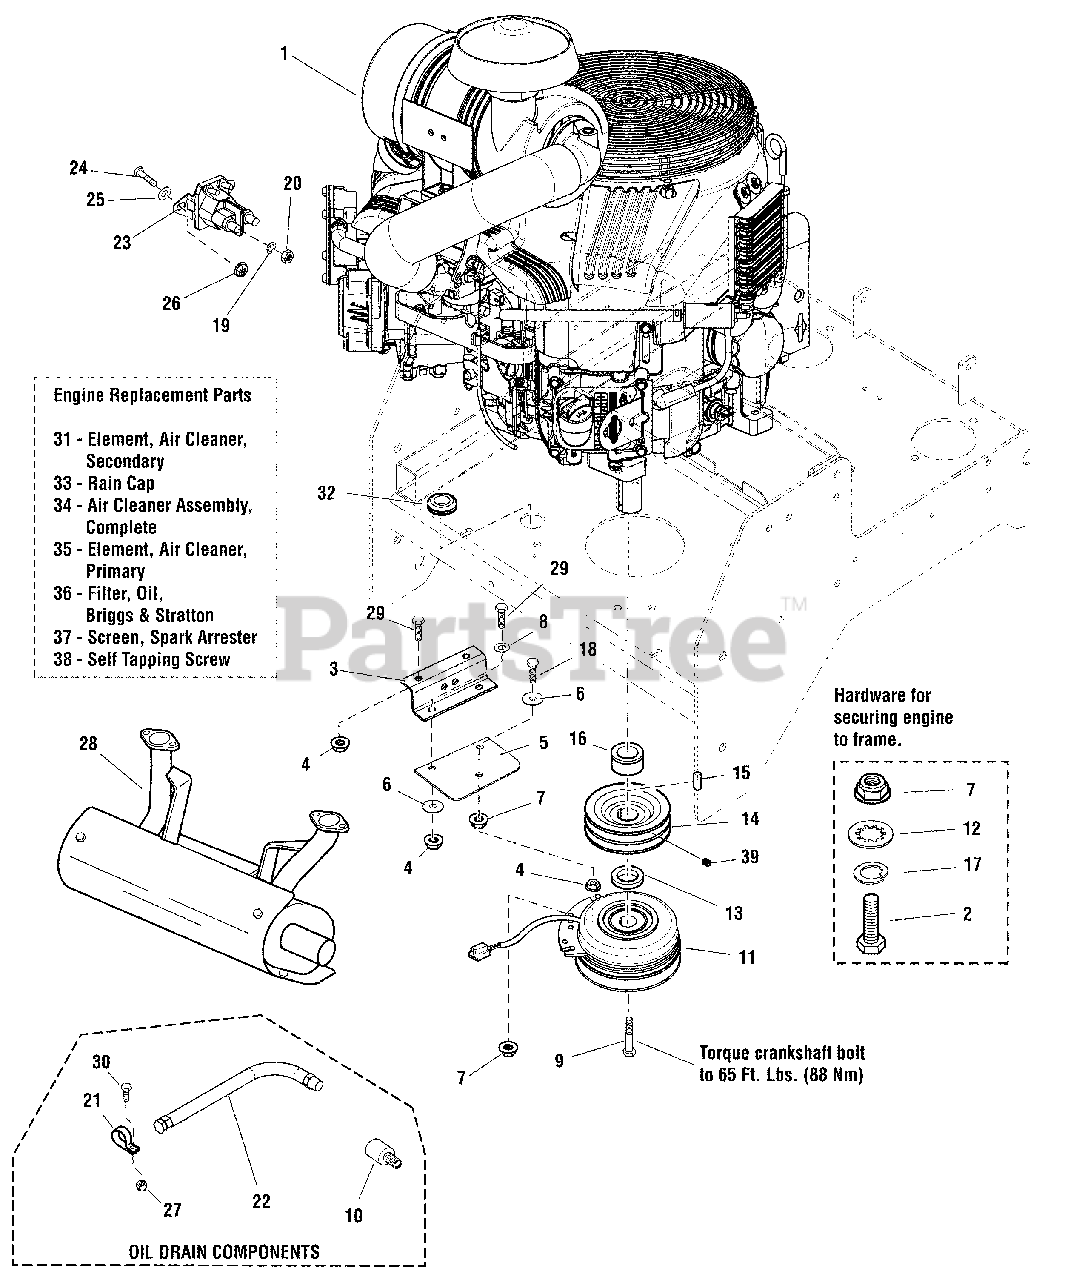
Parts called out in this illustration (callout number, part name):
1	* ENGINE, Briggs & Stratton
2	BOLT, 5/16-18 X 1-3/4 GD5 YZ
3	ANCHOR, CLUTCH - BLK
4	NUT, 5/16-18 HEX SERRATED FLANGE, LARGE
5	CLUTCH ANCHOR PAD
6	WASHER-3/8 FENDER
7	NUT, 5/16-18 HEX NYLOCK FLANGE
8	WASHER, 5/16" SAE
9	BOLT, CRANKSHAFT, 7/16X2-1/2
10	METRIC ADAPTER, M14-1.5" TO 3/8 NPTF
11	CLUTCH, WARNER,# 5218-158
12	WASHER, 5/16 INT. TOOTH LOCK
13	SPACER, 1.13 X 1.75 X .50
14	PULLEY, 5.25 OD X 1.126 ID
15	KEY, 1/4 SQ. X 1.00
16	SPACER, 1.13 X 1.75 X 1.09, PM
17	WASHER, 5/16" LOCK
18	BOLT, 5/16-18 X 3", FLT
19	WASHER, LIGHT LOCK, 5/16
20	NUT, HEX JAM, 5/16-24
21	CLAMP, VINYL
22	HOSE, OIL DRAIN
23	SOLENOID-4 POLE 12 VOLT DC (TROMBETTA)
24	BOLT, 1/4-20 X 3/4"GD5 YZ
25	WASHER, 1/4 SAE (5025154)
26	NUT, 1/4-20 HEX SERR. FLANGE
27	NUT, 1/4-20 HEX NYLOCK FLANGE (5025391)
28	MUFFLER, EXHAUST ASSY
29	BOLT, 5/16-18 X 1 GD5 YZ
30	BOLT, 1/4-20 X 1" GD5 CZ
31	ELEMENT, AIR CLEANER, SECONDARY
32	GROMMET, 7/8
33	CAP, A/C RAIN
34	AIR CLEANER ASSEMBLY, 5"
35	ELEMENT, AIR CLEANER, PRIMARY
36	FILTER, OIL, BRIGGS & STRATTON
37	SCREEN, ARRESTER
38	SCREW,SELF-TAP,#8-32 X 3/8,WASH HEX, CZ
39	SET SCREW, 5/16-18 X 3/8, KNURL, W/PATCH
40	TIE WRAP, 24" LONG
